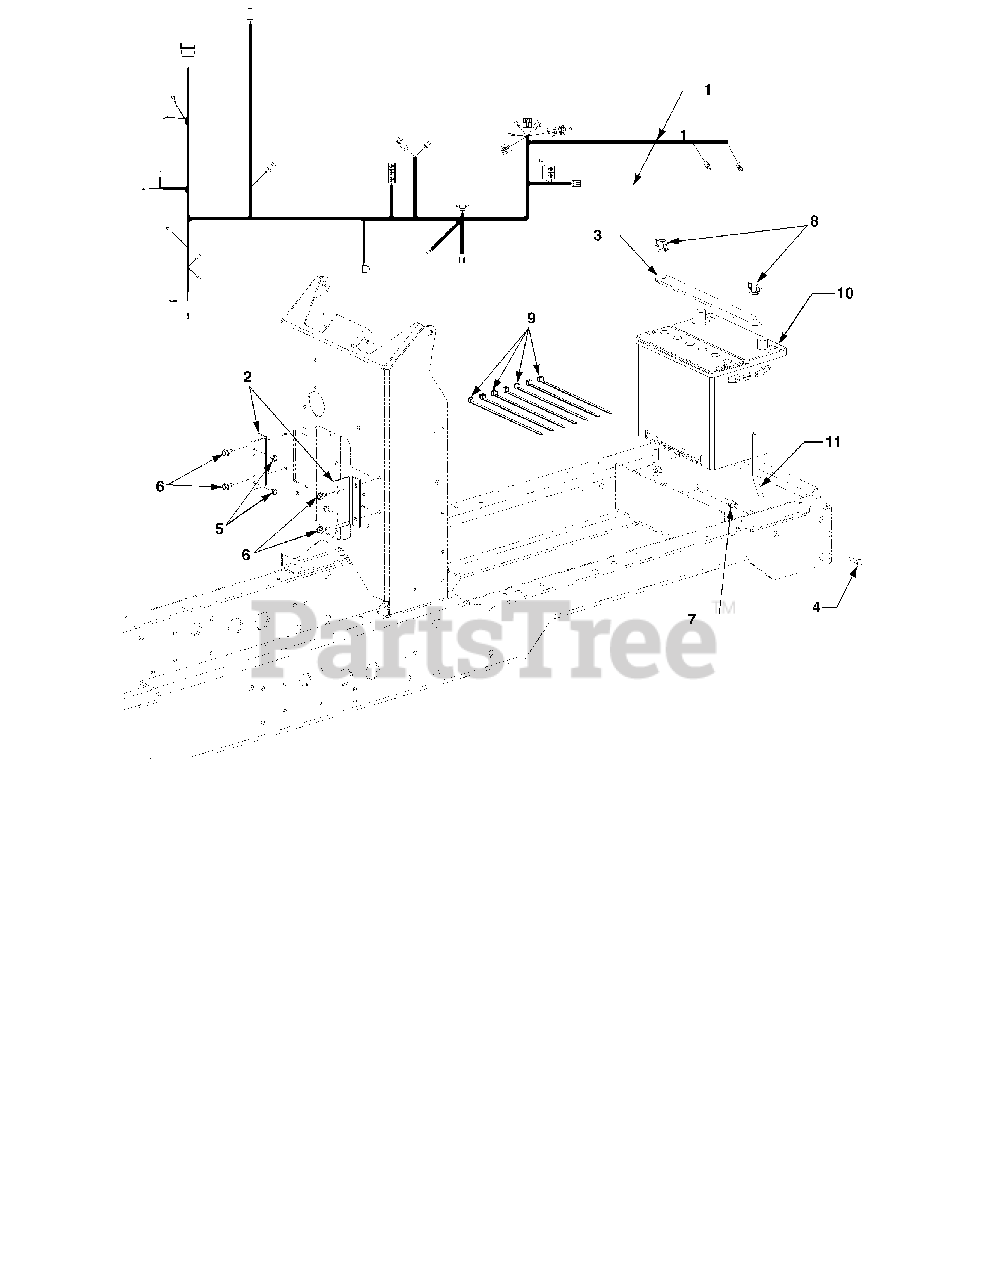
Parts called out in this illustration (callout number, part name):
1	Harness, Main Wire
2	Bracket, Relay Mtg.
3	Strap, Battery Holddown
4	Screw, Hex Cap, 1/4-10 x .875 GR5
5	Screw, Hex Wash Hd. Tapp #10-16 x .5
6	Screw, Hex Wash Hd. Tapp 1/4-20 x .5
7	Nut, Hex Nylon Insert Lock, 1/4-20
8	Nut, Wing w/Bell Washer, 5/16-18
9	Tie, Cable
10	Battery, 500 cca Dry
11	Rod, Battery Holddown
